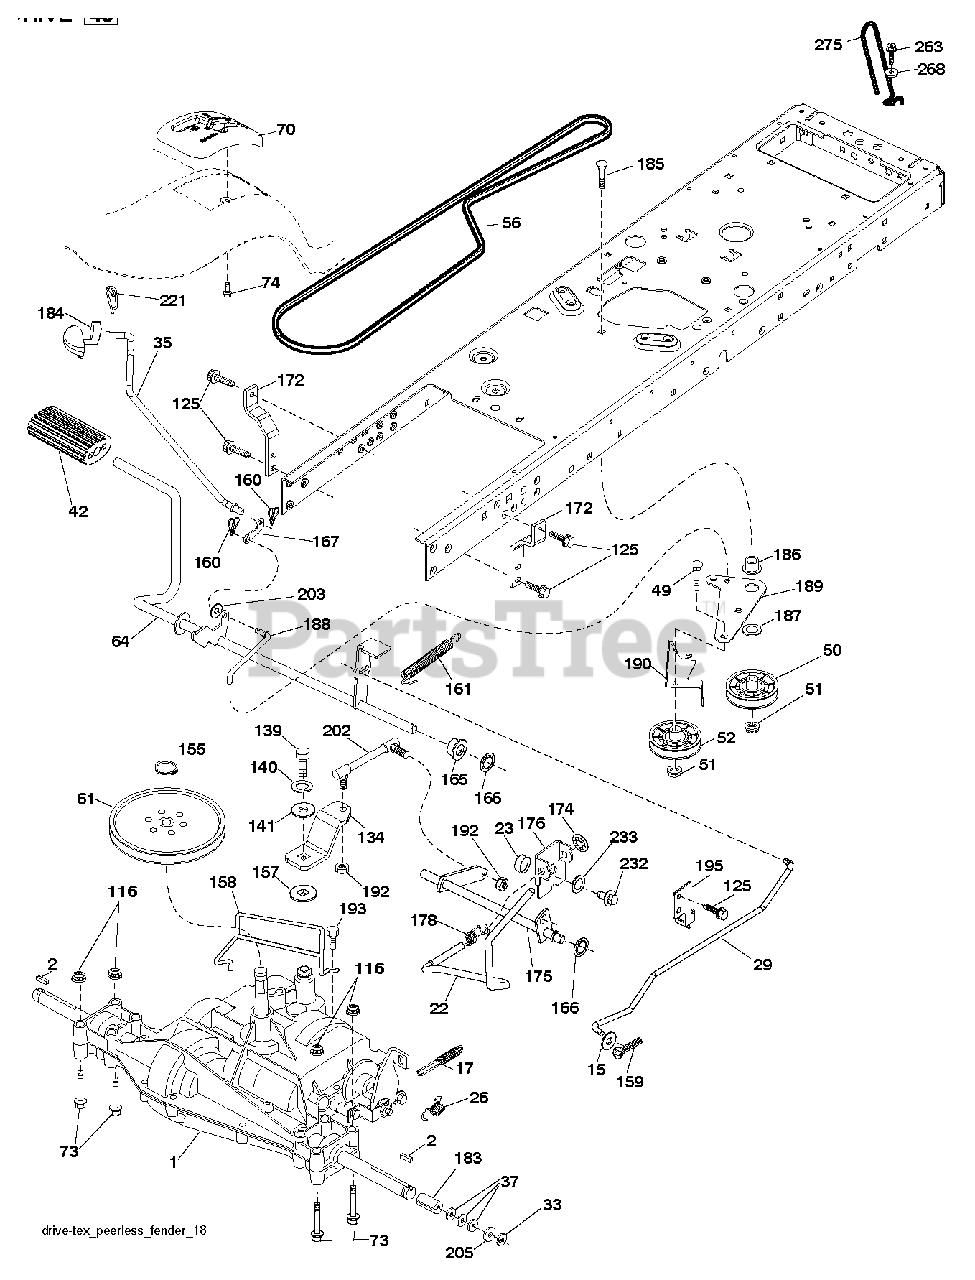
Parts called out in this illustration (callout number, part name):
2	SQUARE KEY
17	SPRING.BRAKE.PEERLESS.TEX
22	ROD.SHIFT.FENDER.TLT.2006
23	KNOB.DUCKHEAD.1/2
26	SPRING.BRAKE.RTN.GR.DR
29	ROD.BRAKE.PEERLESS
33	E-RING LT
35	ROD, BRAKE, PARK
42	PEDAL COVER T
49	BOLT
50	IDLER.FLAT.910.OFFSET
51	NUT LOCK FLG 3/8-16 UNC
52	IDLER.V-GROOVE.910.OFFSET
56	V-BELT.TRACTOR.DRIVE.P
61	PULLEY TRANS
64	SHAFT.ASM.PEDAL.BRAKE.
70	CONSOLE.SHIFT.
73	BOLT HEX 5/16-18 GR 5
74	SCREW.HI-LO.CONSOLE
116	NUT LOCK HEX FLANGE 5/16-18
125	SCREW
134	ARM SHIFT
139	BOLT 1/4-28X3/4
140	LOCKWASHER
141	WASHER LT
155	RETAINING RING LT
157	WASH-SHFT PLT LT
158	KEEPER.PMS.18/20.D4365
159	COTTER PIN
160	RETAINER CLIP
161	SPRING, RETURN LT
165	BUSHING.SHAFT.BRAKE.HAND
166	NUT.PUSH.625
167	LATCH.BRAKE.SPRING
172	STRAP.TRQ.LH.GEAR.DRIV
174	NUT.PUSH.500.2006
175	SHAFT ASM SHIFT
176	ARM.CLEVIS.ROD.SHIFT
178	SPRING.SHIFT.GT2006
183	SPACER AXLE
184	HANDLE PARKING BRAKE
186	SPACER.RETAINER
187	WASHER 12/32X2X10GA
188	LINK.CLUTCH.GROUND.DRIVE
189	BELLCRANK.GROUND.DRIVE.TEX.
190	KEEPER.BELLCRANK.DRIVE
192	NUT LOCK CENTER 1/4 -28 FNTHD
193	SCREW 5/16"
195	BRKT.ROD.BRAKE.PEERLES
202	LINK.SHIFT.PMST.18"
203	WASHER
221	RETAINER.SPRING.CLIP.H
232	BOLT FIN HEX 7/16-14 X 1
233	WASHER SERRATED
263	SCREW, 3/8-16X3/4
268	WASHER
